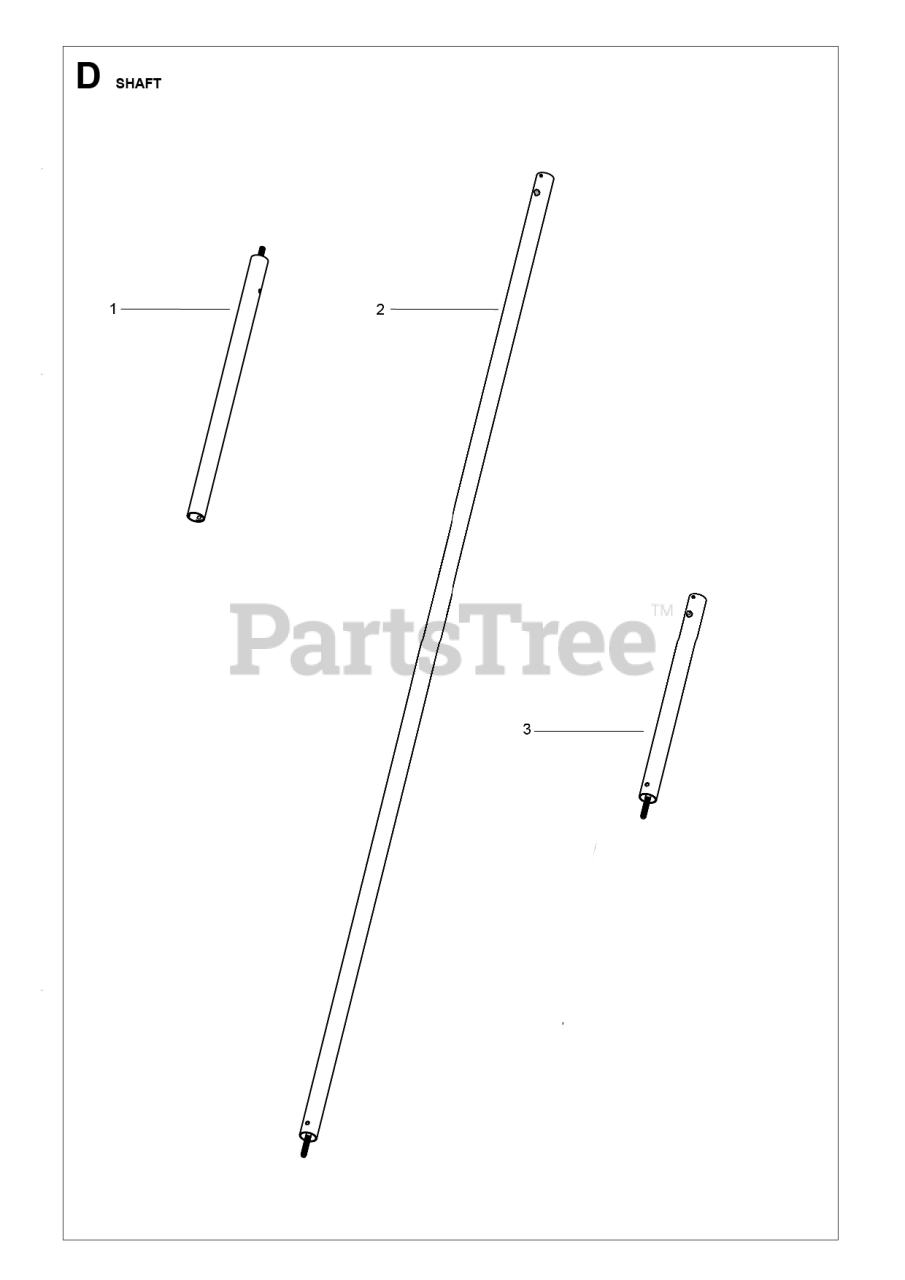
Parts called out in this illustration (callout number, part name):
1	TUBE DS ASSY
2	TUBE DS ASSY
3	TUBE DS ASSY
